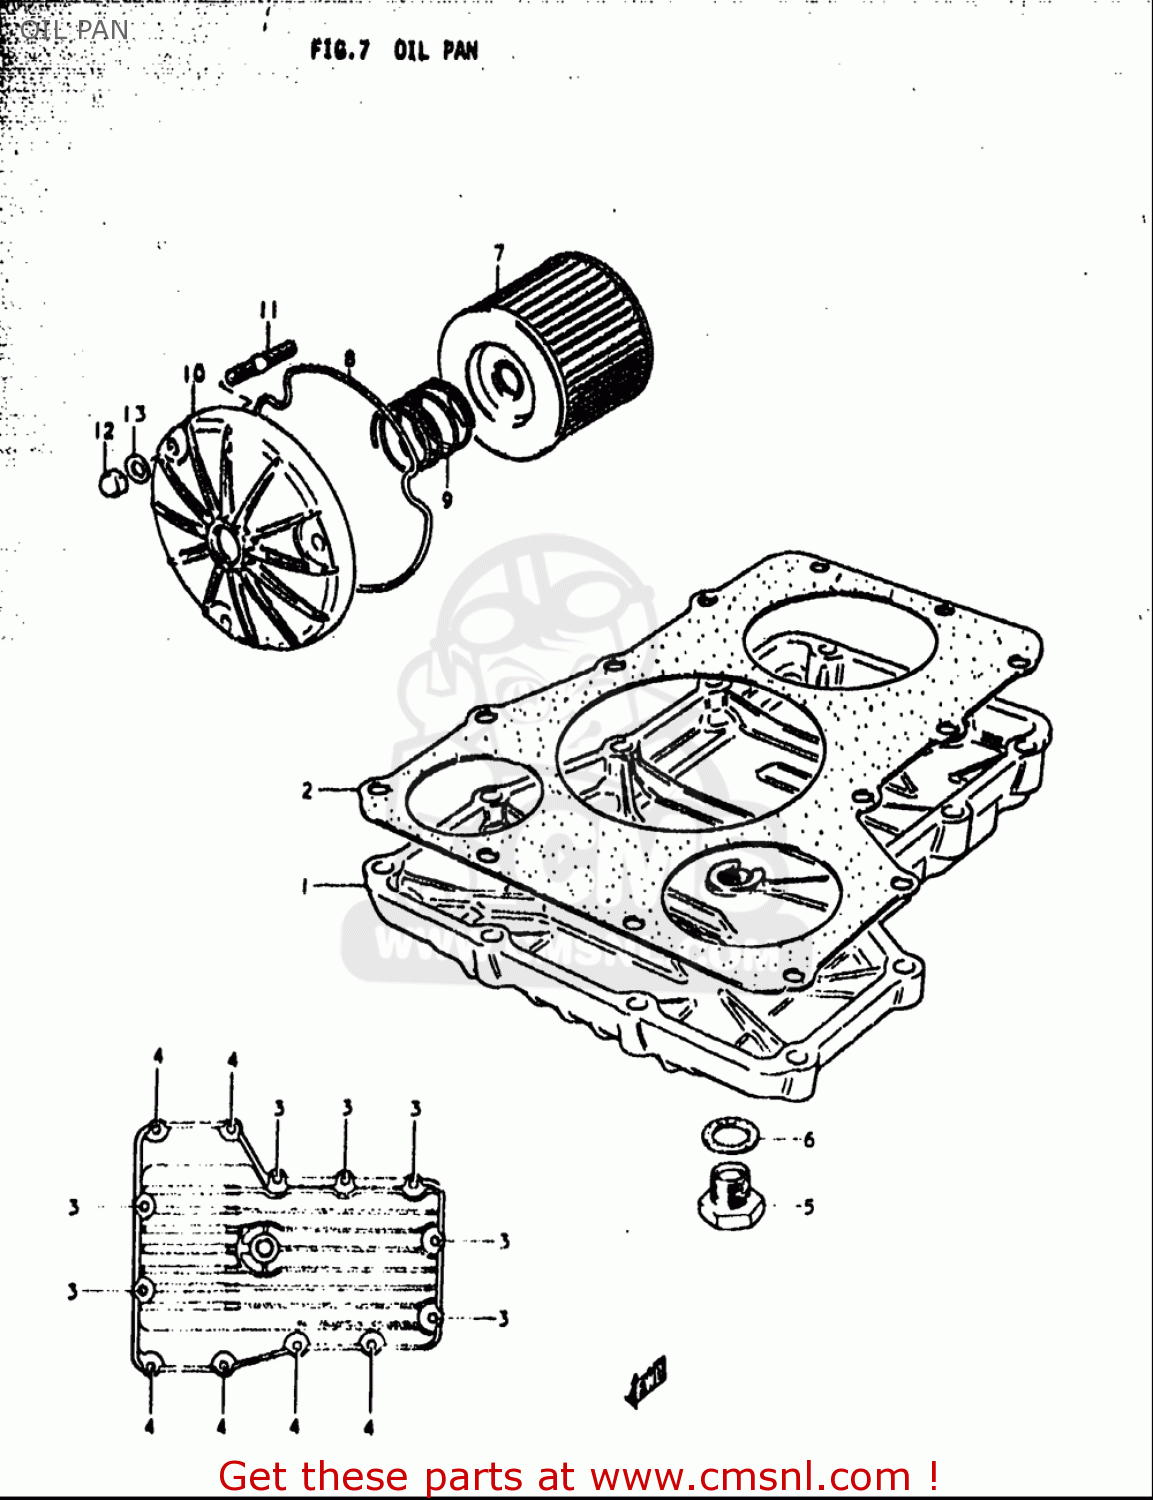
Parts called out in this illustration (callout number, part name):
1	PAN,OIL
2	GASKET,OIL PAN (NAS)
3	BOLT
4	BOLT
5	PLUG(MAGNETO)
6	GASKET(14X19.2X2) (NAS)
7	FILTER ASSY,ENGINE OIL
8	O RING,OIL FILTER CHAMBER CAP
9	SPRING
11	BOLT,STUD
12	NUT
13	WASHER
